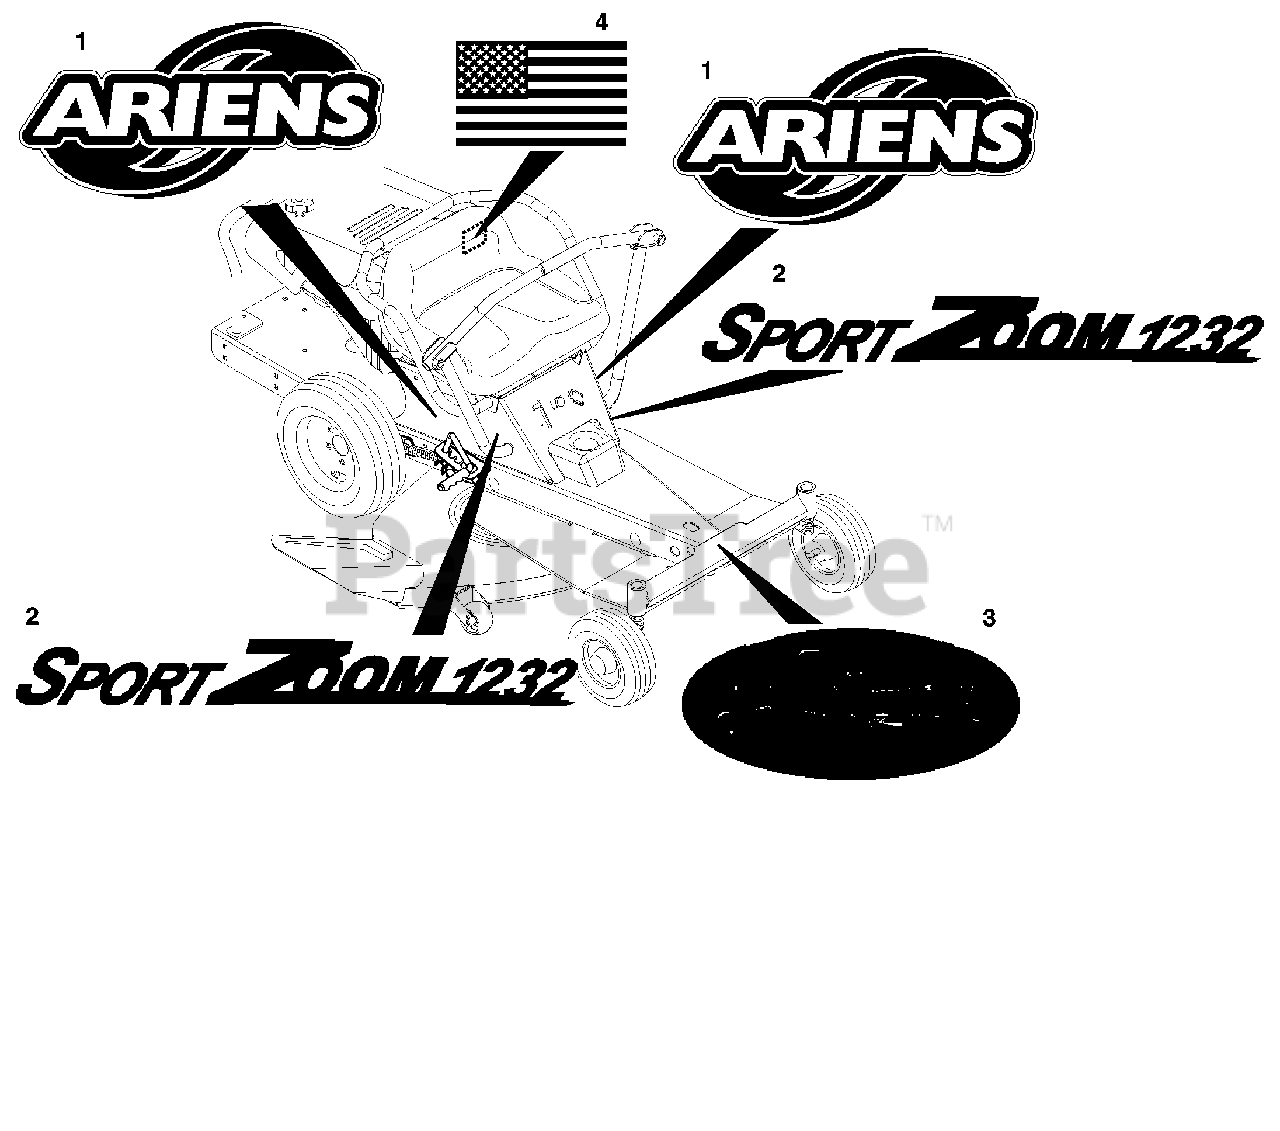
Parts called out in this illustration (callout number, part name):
1	DECAL-ARIENS ZOOM
2	DECAL-SPORT ZOOM 1232
3	DECAL-ARIENS JEWEL
4	DECAL, AMERICAN FLAG
